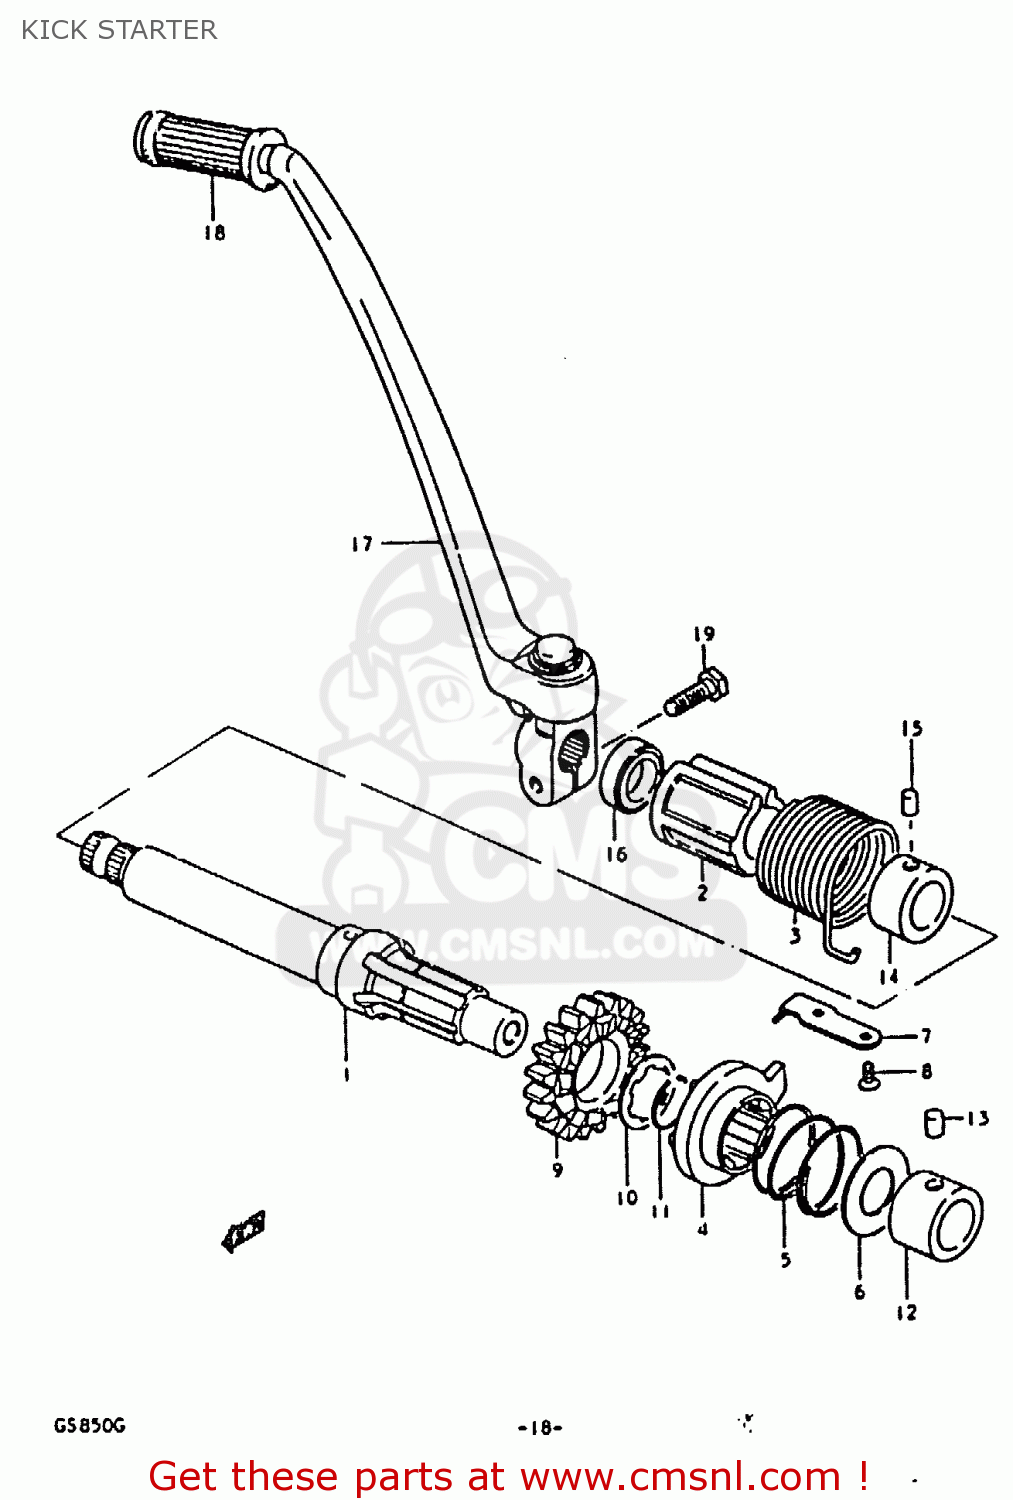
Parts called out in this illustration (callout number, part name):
1	SHAFT,KICK STARTER
2	GUIDE,KICK SHAFT SPRING
3	SPRING
4	STARTER,KICK
5	SPRING
6	WASHER
7	GUIDE,STARTING SPRING
8	SCREW
9	GEAR,KICK STARTER DRIVE
10	WASHER,LOCK
11	CIRCLIP
12	BUSHING
13	PIN
14	BUSHING
15	PIN
16	SEAL,OIL(20X27X5)
17	LEVER ASSEMBLY,KICK STARTER
18	RUBBER,KICK STARTER PEDAL
19	BOLT
